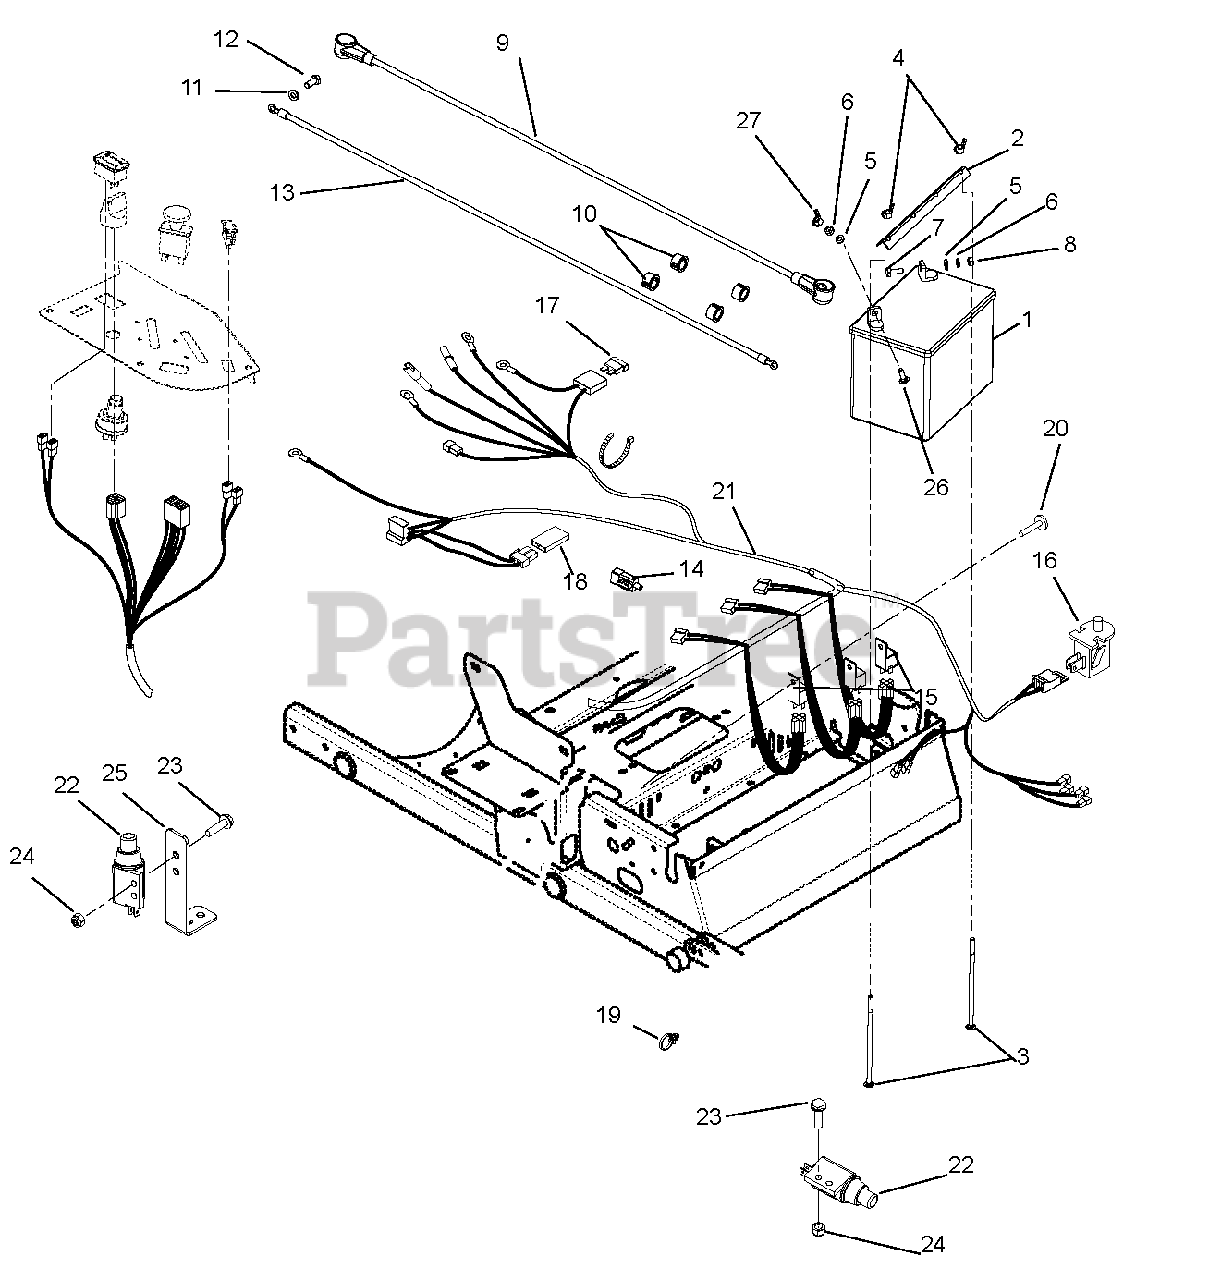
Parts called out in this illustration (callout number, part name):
1	Battery, SMF U1-9U1L/U1H
2	Hold Down
3	Bolt, Round Head Square Neck .25-20 x 7.50
4	Nut, Locking Wing .250-20
5	Washer, Flat Steel .281 x .62 x .065
6	Washer, Locking .25 x .062 Regular
7	Bolt, Hex .25-20 x .75 Grade 5
8	Nut, Hex .25-20
9	Cable, POS Battery with Boots 6 x 35
10	Bushing, Panel Snap .687 x .875 x .56
11	Washer, Locking .31 x .078 Regular
12	Bolt, Hex M8-1.25 x 20
13	Cable, Negative Battery 35.0"
14	Switch, Snap-In – N.O./N.O.
15	Relay (Included with Harness)
16	Switch, Snap Mounting
17	Fuse, 30 Amp (Included with Harness)
18	Diode, Connector Shell
19	Cable Tie with TREE (.25 HOLE)
20	Rivet, .25 Nylon Panel
21	Harness, Vertical A/C Wiring
22	Switch, Single Pole (N.O.) with Cover
23	Screw, Machine 10-24 x .75 Hex Washer Head
24	Nut, Locking Nylon 10-24 with Insert
25	Mount, Switch PT200 CE
26	Bolt, Round Head Square Neck .25 -20 x .75 Gr 5 YZ
27	Nut, Wing .25-20 YZ
